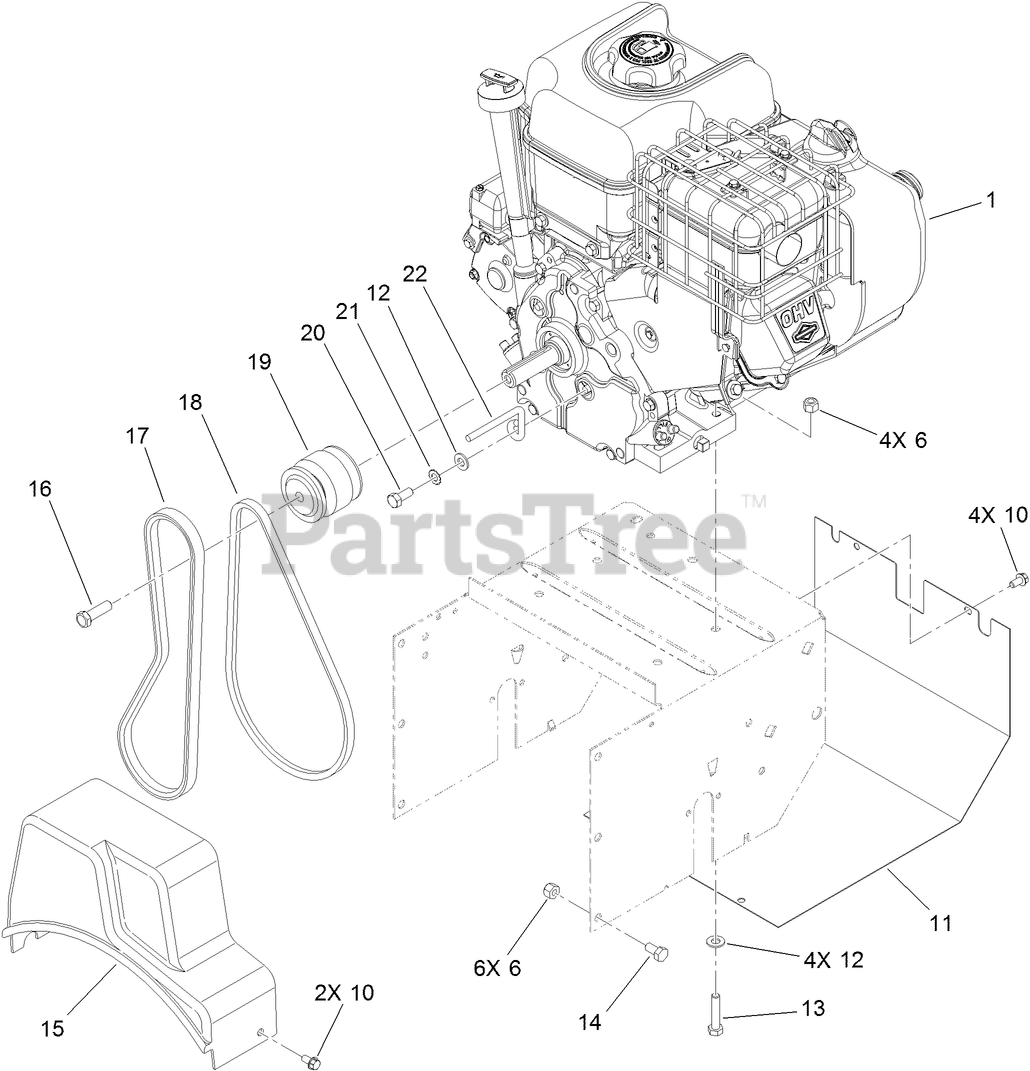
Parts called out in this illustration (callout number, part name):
6	NUT-LOCK, NI
10	SCREW-HWH
11	COVER-TRACTION, LOWER
12	WASHER-PLAIN
13	SCREW-HH
14	SCREW-HH
15	COVER-BELT
16	SCREW-SPECIAL
17	V-BELT
18	V BELT-3L, TRACTION
19	PULLEY-ENGINE
20	SCREW-HH
21	WASHER-LOCK
22	RETAINER-BELT
